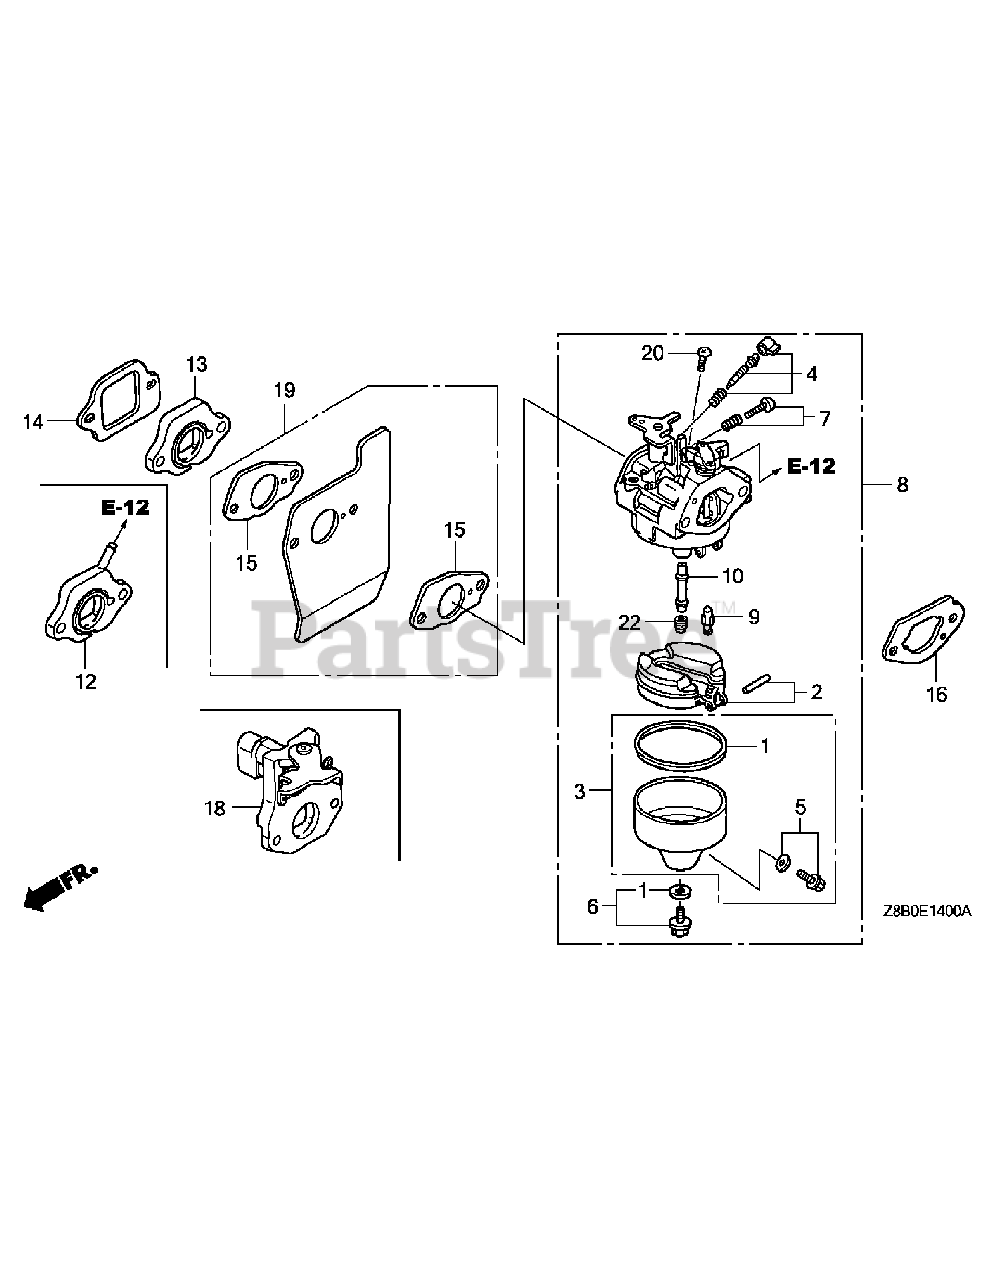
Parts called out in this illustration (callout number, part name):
1	GASKET SET
2	FLOAT SET
3	CHAMBER SET, FLOAT
5	SCREW SET, DRAIN
6	SCREW SET
8	CARBURETOR ASSY. (BB65A A) (Honda Code
9	VALVE, FLOAT
10	NOZZLE, MAIN
13	INSULATOR, CARBURETOR
14	GASKET, INSULATOR
15	GASKET, CARBURETOR
16	GASKET, CARBURETOR
19	GUIDE, AIR
20	SCREW, PAN (5X6)
22	JET, MAIN (#60)
22	JET, MAIN (#62)
22	JET, MAIN (#65)
